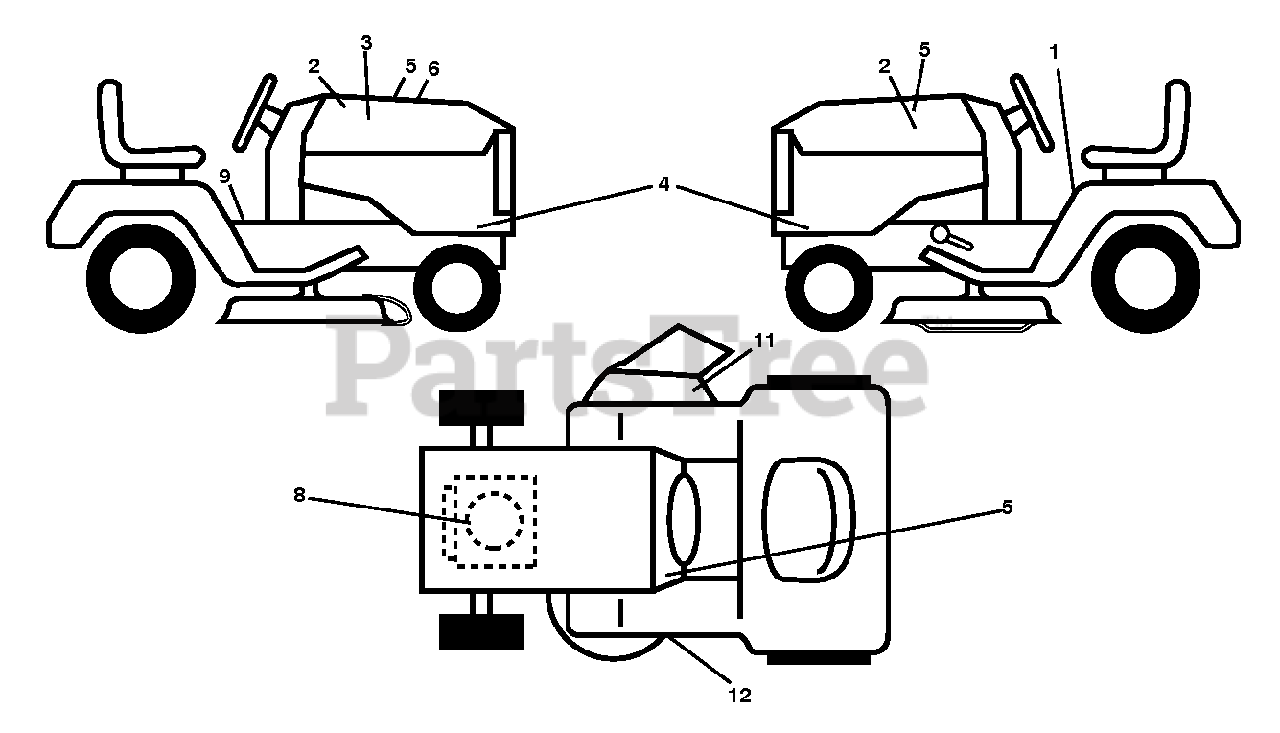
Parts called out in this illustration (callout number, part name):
1	DECAL.FENDER.WARNING.ENGLISH
2	DECAL.BADGE.170MM.TEXTLOGO.
3	DECAL.RPL.TLW.M33.42.VATR
4	DECAL.SDPNL.YTA18542.SET.HUSQ
5	DECAL.SNOWFLAKE.MS498.HUSQ
6	DECAL.WARNING.CUST.RESP.E85.
8	DECAL.BS.ENDUR.18_5HP.382024
9	DECAL BTRY SYMBOLS
11	DECAL.MOWER.WARN.KEEP.HAND.AWY
12	DECAL.V-BELT.SCH.42/46"MEC/ELE
